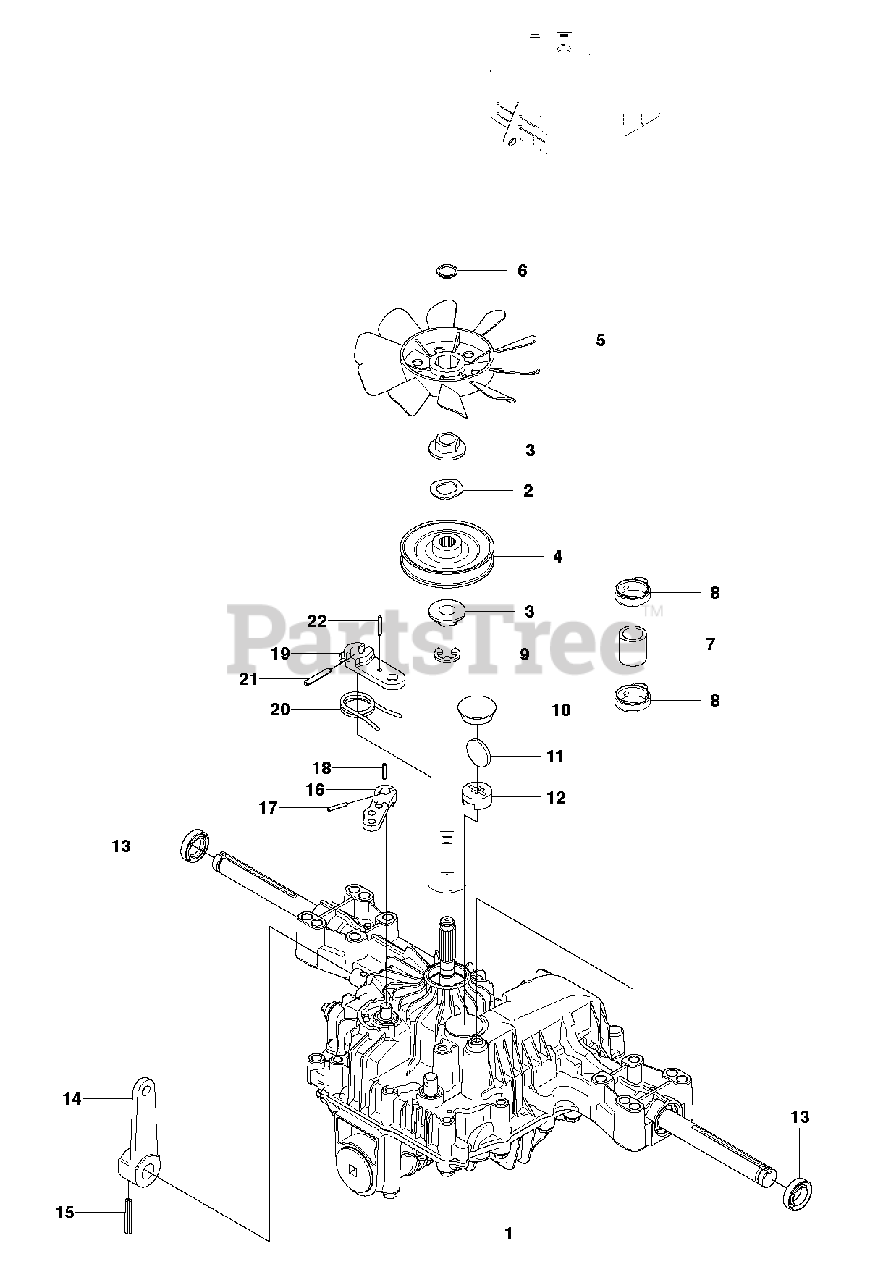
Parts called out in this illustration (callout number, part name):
1	HYDRAULMOTOR
2	WASHER **
5	FAN
6	RETAINING RING **
8	CLAMP
9	CLIP
10	PLUG
11	MAGNET
12	MAGNET HOLDER
13	SEALING
14	CONTROL LEVER
15	PIN
16	ARM
17	PIN
18	PIN
19	ARM
20	RETURN SPRING
21	PIN
22	PIN
